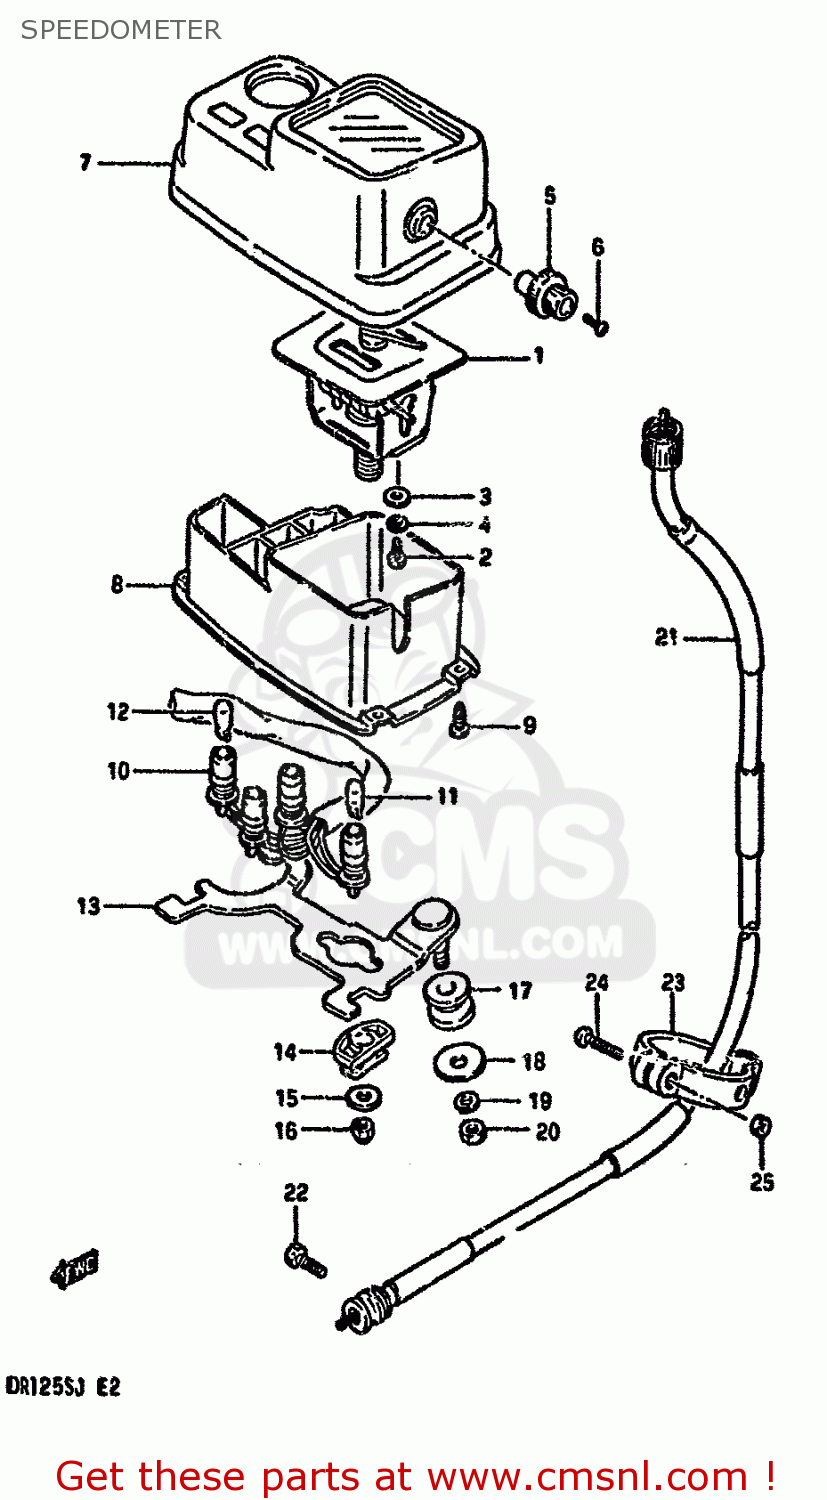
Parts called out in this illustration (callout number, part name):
1	SPEEDOMETER (KILO)
2	SCREW
3	WASHER
4	LOCK WASHER
5	KNOB,TRIP
6	ROTOR,SPEED
7	HOOD,METER
8	CASE,METER
9	SCREW
10	SOCKET,METER
11	BULB(6V,3W)
12	BULB(12V1.7W,T10,WB121)
13	BRACKET,METER
14	CUSHION
15	WASHER
16	NUT
17	CUSHION
18	WASHER
19	WASHER,LOCK
20	NUT
21	CABLE ASSEMBLY,SPEEDOMETER
22	BOLT
23	CLAMP,SPEEDOMETER CABLE
24	SCREW
25	NUT ,5MM
